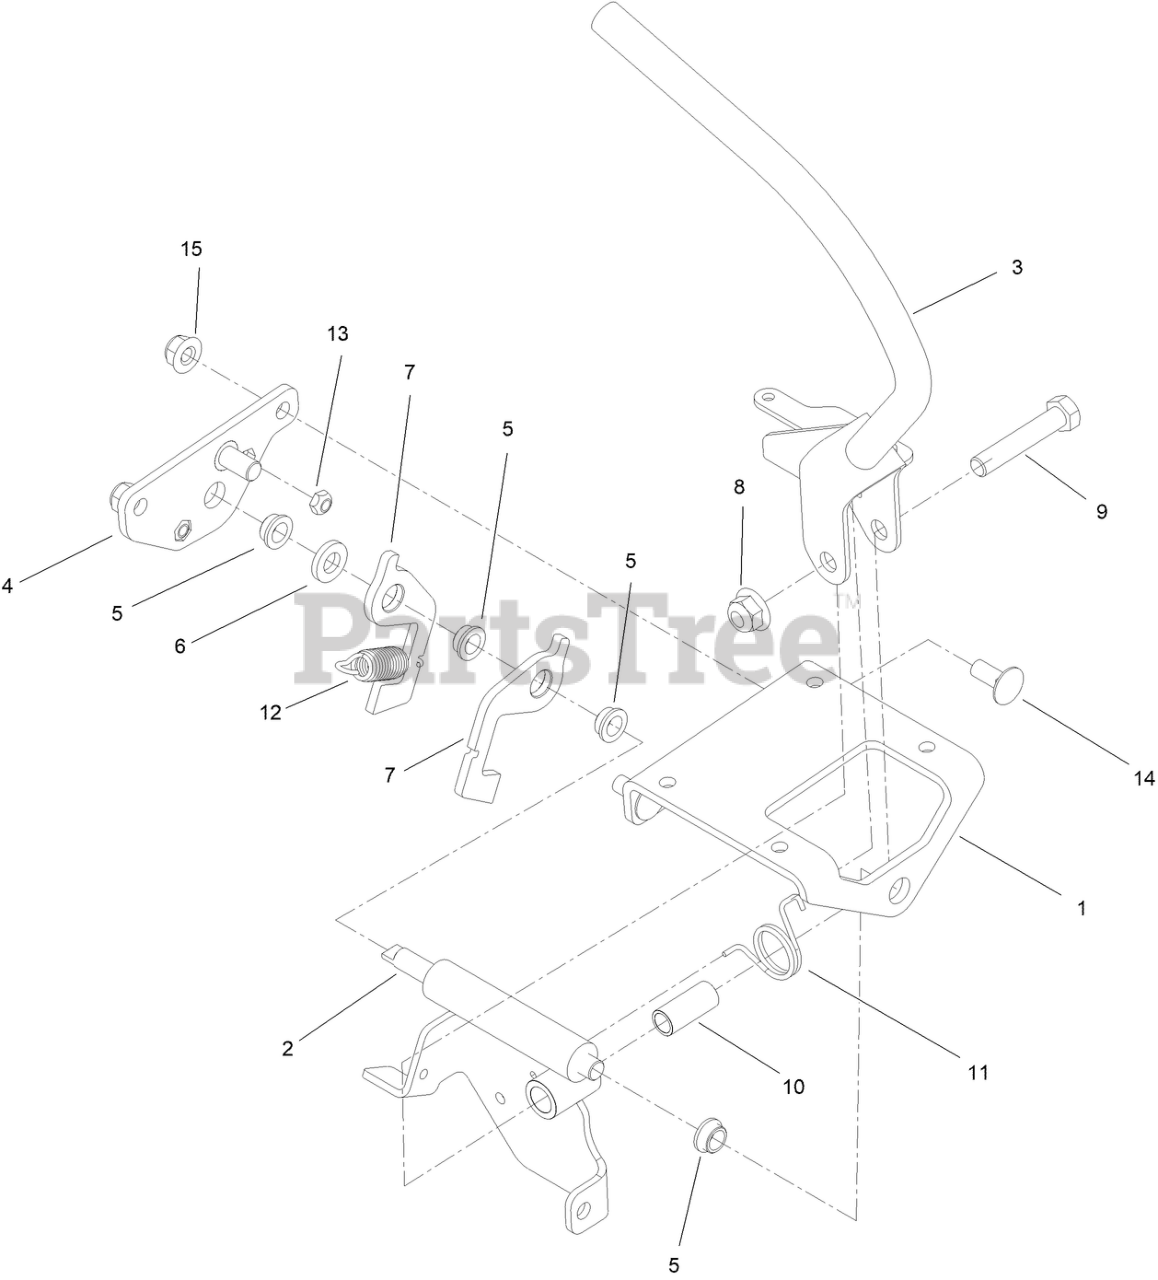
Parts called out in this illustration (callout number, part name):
1	BRACKET-CONTROL MOUNT
2	MOTION CONTROL ASM LH
3	LH LEVER ASM
4	PLATE ASM-SENSOR LH
5	BUSHING-FLANGED NYLON
6	WASHER
7	PLATE-SPRING
8	NUT-HF, NI
9	SCREW-HH
10	BEARING-SLEEVE
11	SPRING-TORSION
12	SPRING-EXTENSION
13	NUT-LOCK, NI
14	SCREW-CARR
15	NUT-HF, NI
